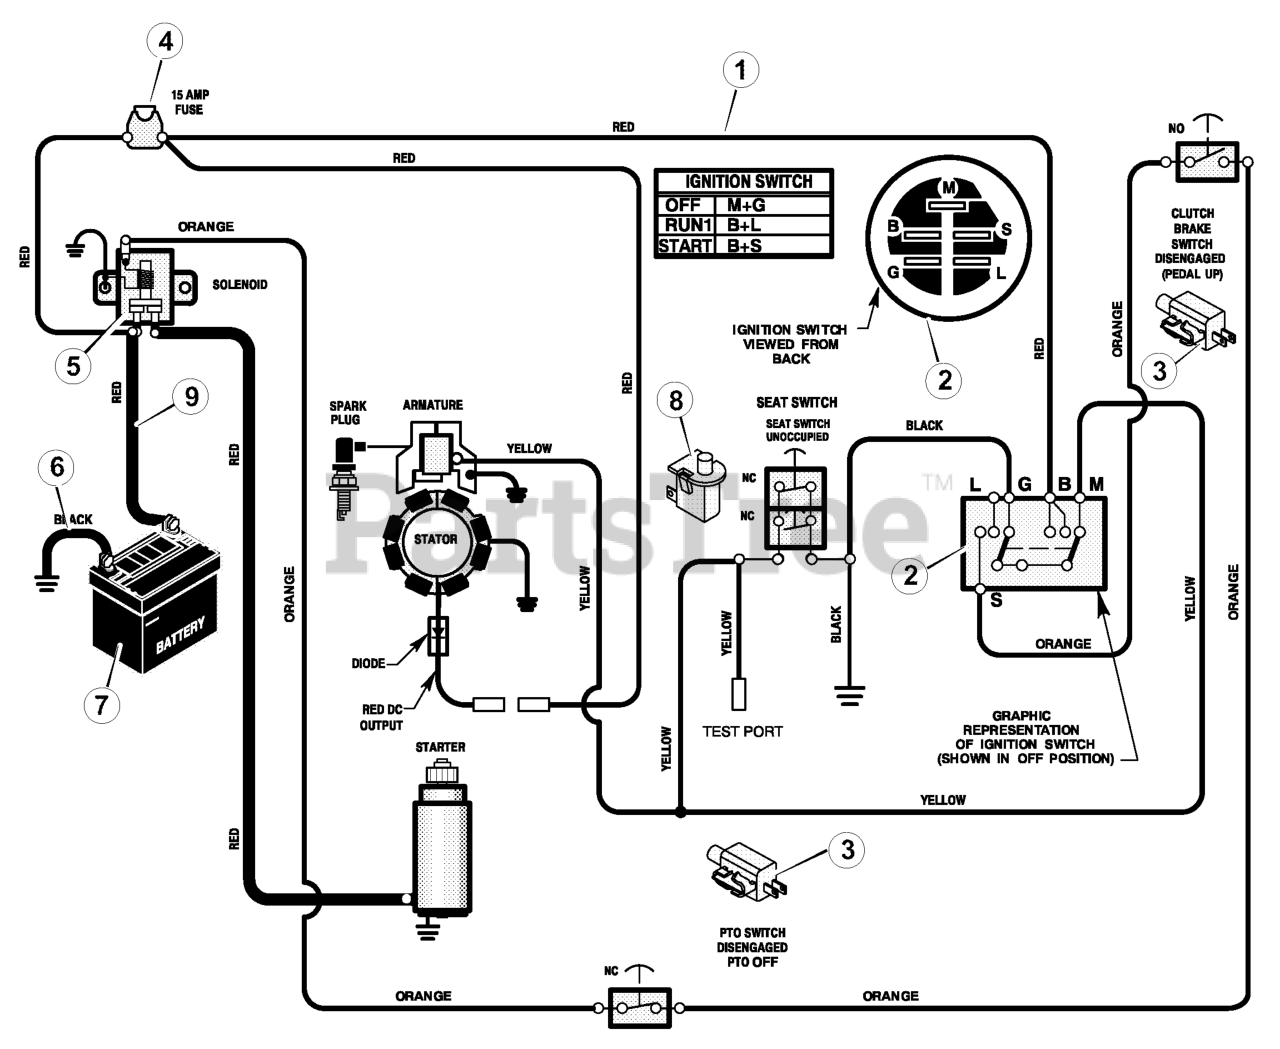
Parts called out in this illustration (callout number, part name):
1	Harness, Chassis Wire
2	Switch, Ignition
3	Switch, Limit
5	Solenoid
6	Cable, Battery Ground
7	Battery
8	Switch, Seat Sensor
9	Cable, Red Battery
